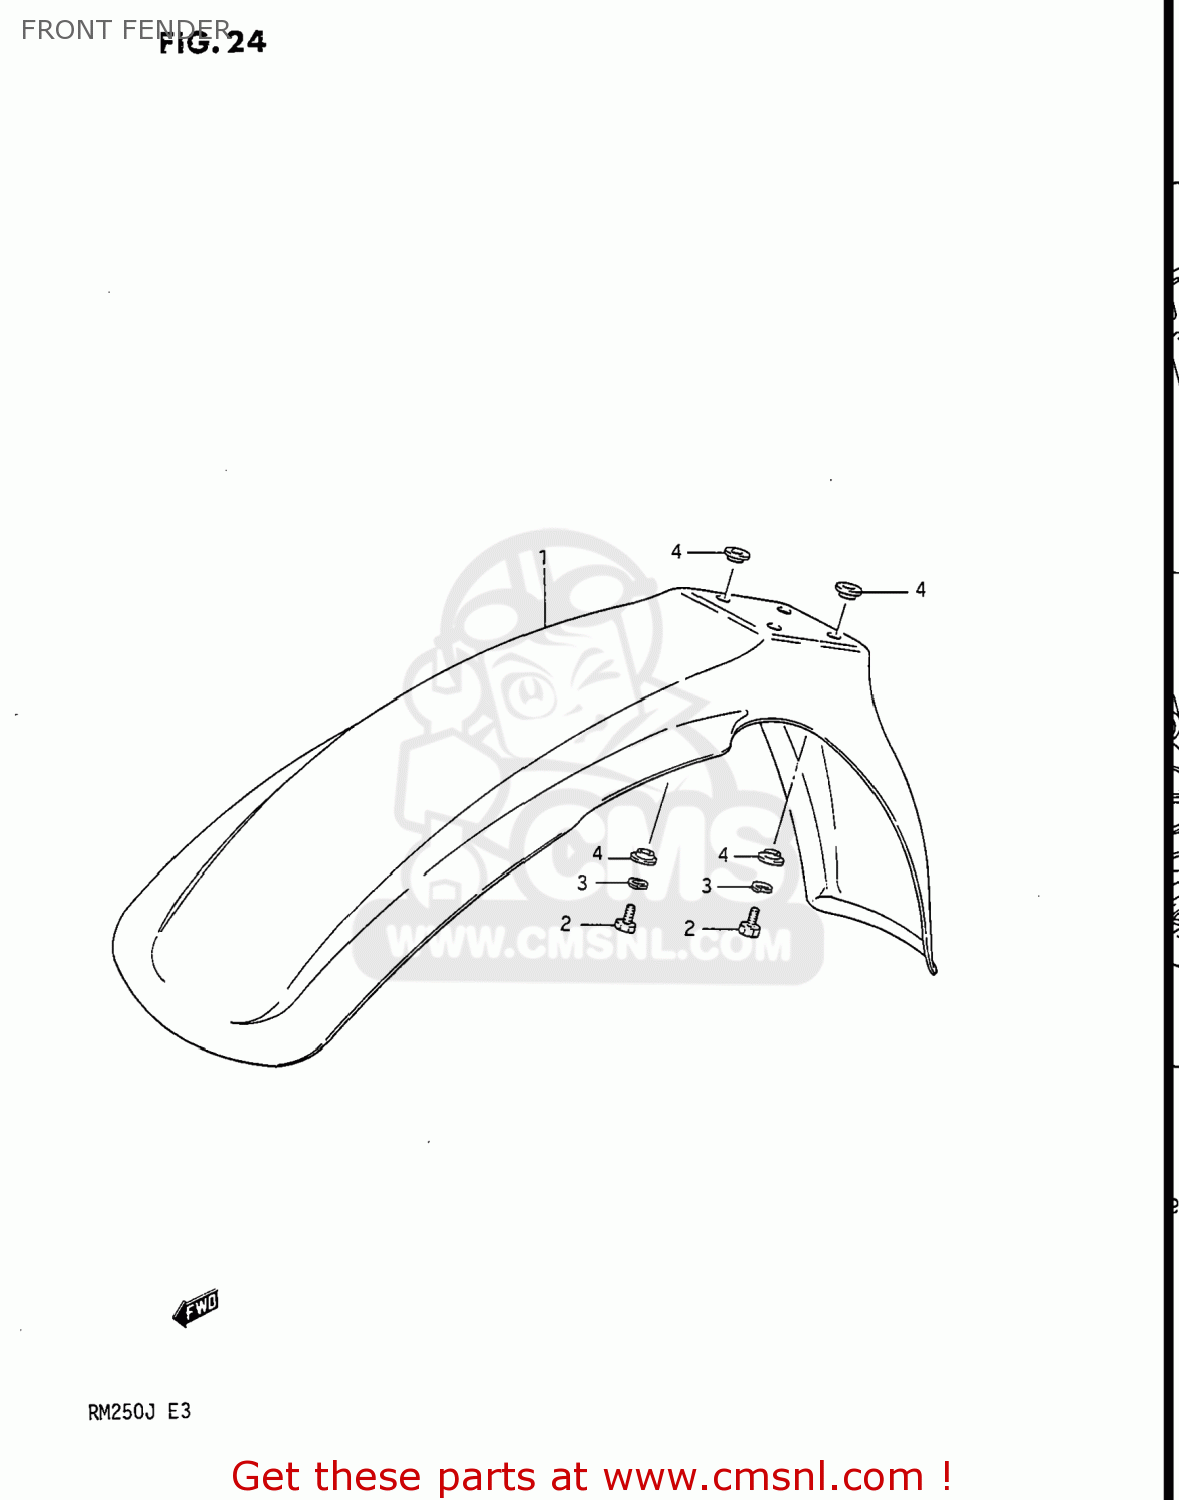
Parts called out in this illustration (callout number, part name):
1	FENDER,FR
2	BOLT
3	WASHER,LOCK
4	WASHER
